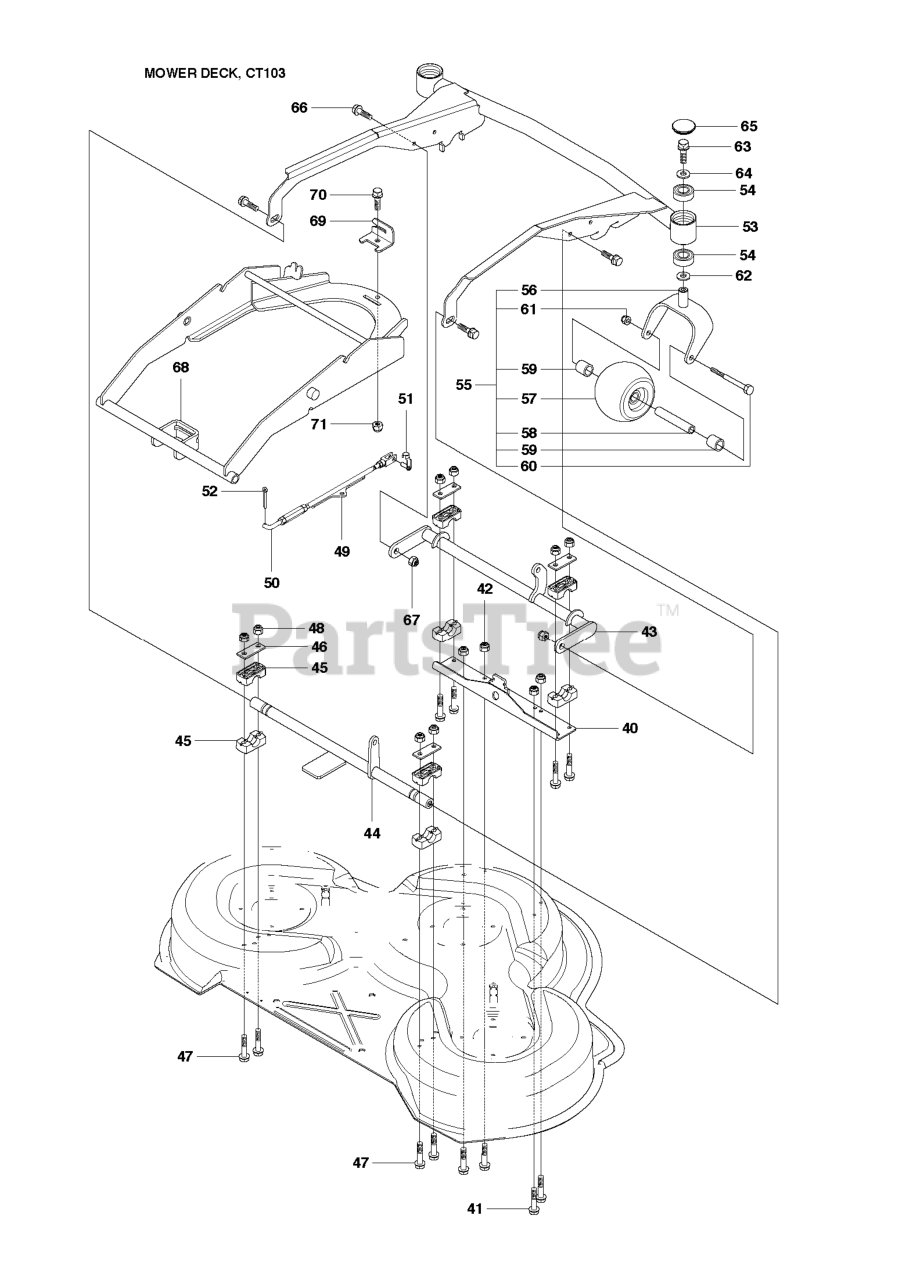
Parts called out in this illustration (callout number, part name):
42	LOCKNUT M8
48	LOCKNUT M8
50	PARALLEL ROD
54	BALL BEARING 6004-2RS1
55	PIVOT WHEELS
57	DECK ROLLER, FRONT
61	NUT
65	HUB CAP PIVOT WHEEL
67	LOCKNUT M8
71	LOCKNUT M8
